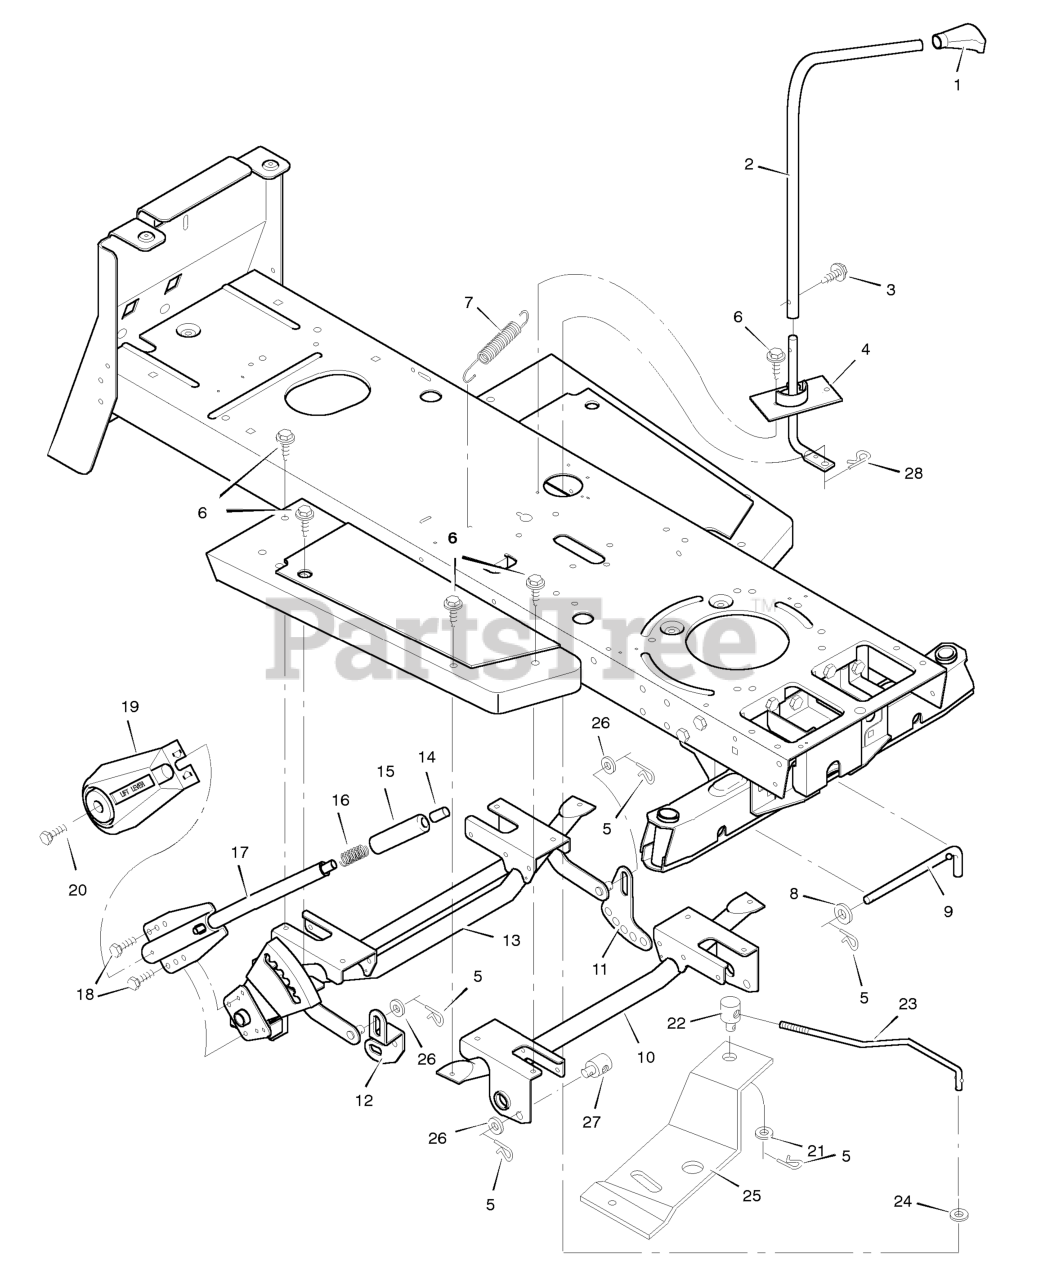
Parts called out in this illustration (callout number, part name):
1	Grip
2	Lever, Blade Control
3	Screw, Hex
4	Control Assembly, Blade
5	Pin, Hair
7	Spring, Extension
9	Pin, Pull
10	Support Assembly, Front
11	Plate, Adjuster
12	Link, Suspension
13	Support, Lifter
14	Button, Push
16	Spring, Compression
17	Handle Assembly
19	Cover, Lift Lever
22	Nut, Adjusting
23	Link, PTO
24	Washer
25	Bracket, Pivot
27	NUT, Adjusting, 1/2-13
28	Pin, Hair
